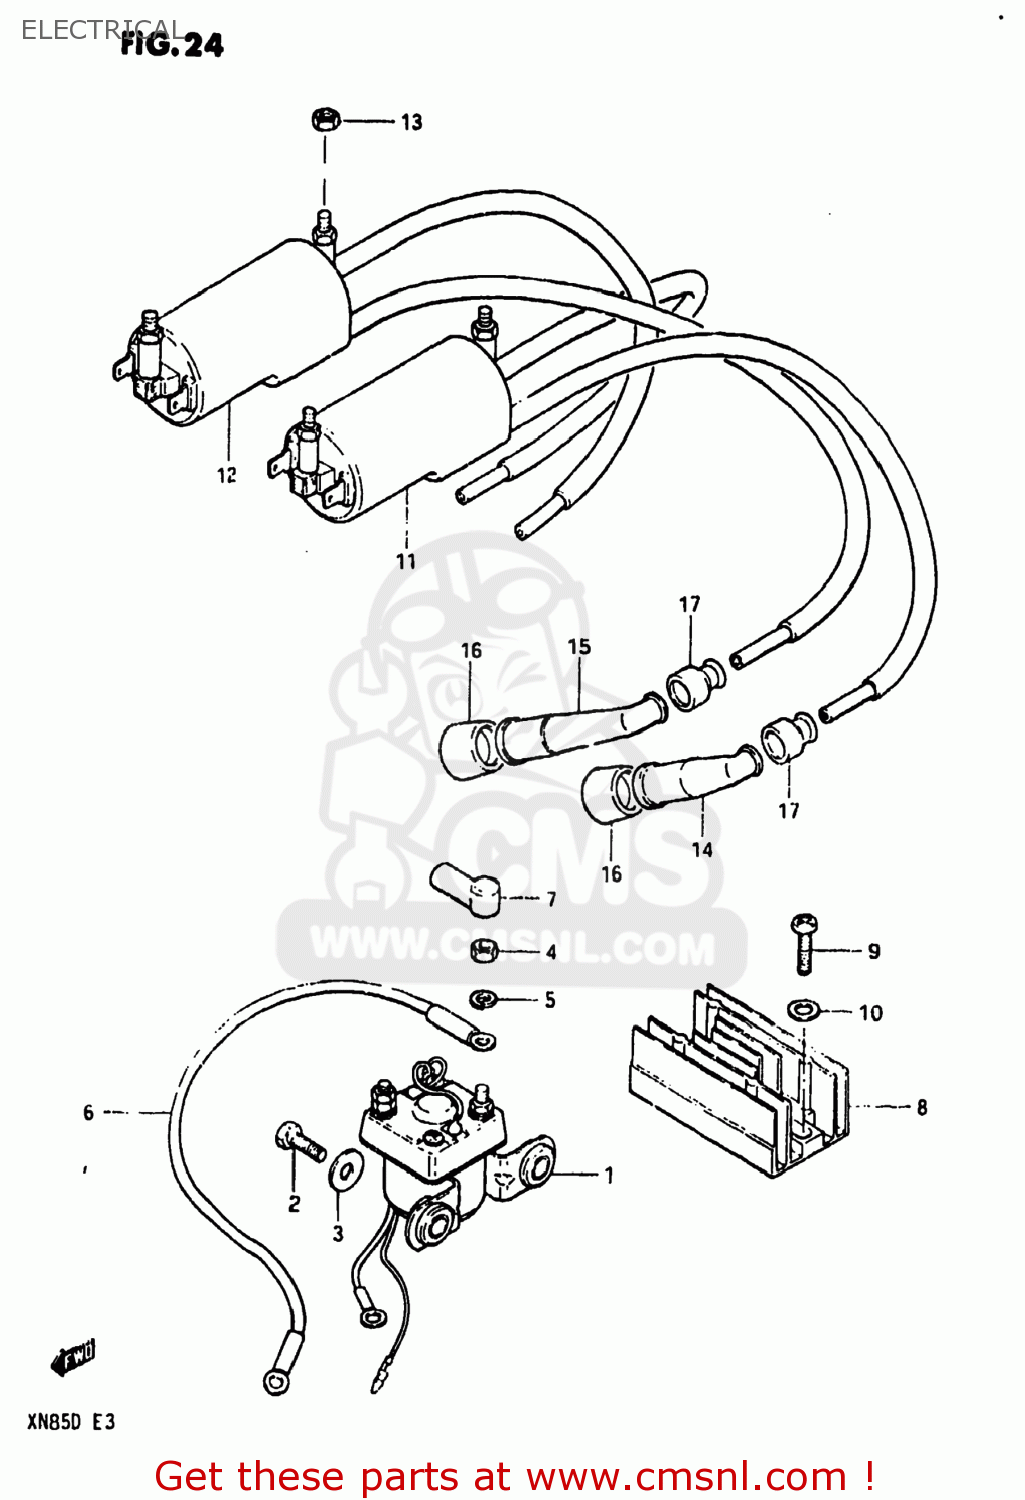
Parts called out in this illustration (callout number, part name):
1	RELAY,STARTER SWITCH
2	BOLT, UPPER
3	WASHER
4	NUT 6MM
5	LOCK WASHER
6	WIRE,STARTER MOTOR LEAD
7	CAP,STARTER RELAY
8	RECTIFIER ASSEMBLY
9	SCREW
10	WASHER
11	COIL ASSEMBLY,IGNITION
12	COIL ASSEMBLY,IGNITION
13	NUT
14	CAP,SPARK PLUG
15	CAP ASSY,SPARK PLUG
16	SEAL,SPARK PLUG
17	SEAL,SPARK PLU
